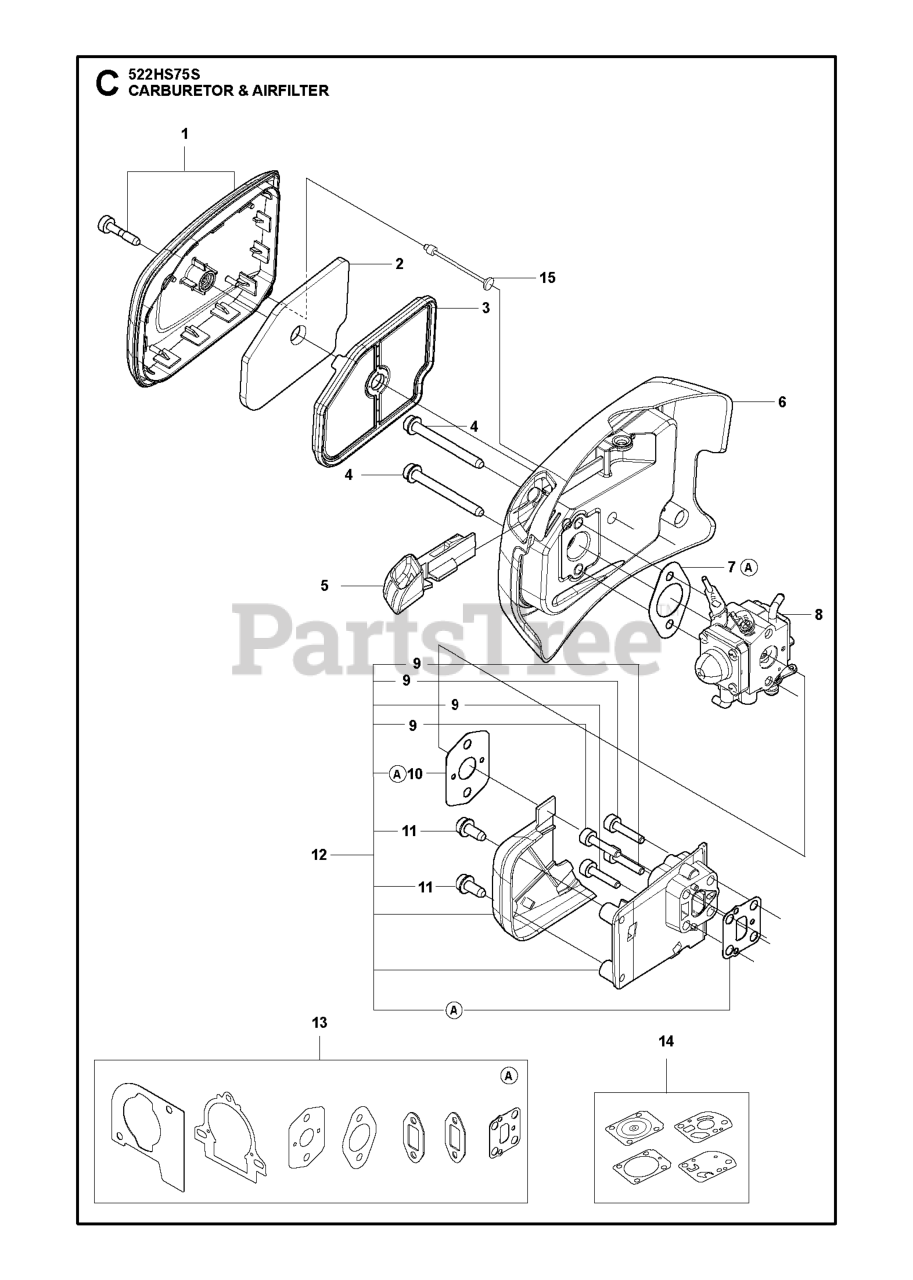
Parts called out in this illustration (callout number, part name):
1	FILTER COVER KIT 522S
2	FILTER FOAM SCAPER
3	FILTER FELT SCAPER
6	FILTER HOLDER ASSY SCAPER
8	CARBURETTOR CARBURETTOR ASSY
11	SCREW ITXSCFT MT5X12 T27 10.9
12	MANIFOLD 522X
13	GASKET KIT 522
14	KIT CARBURETTOR A053
